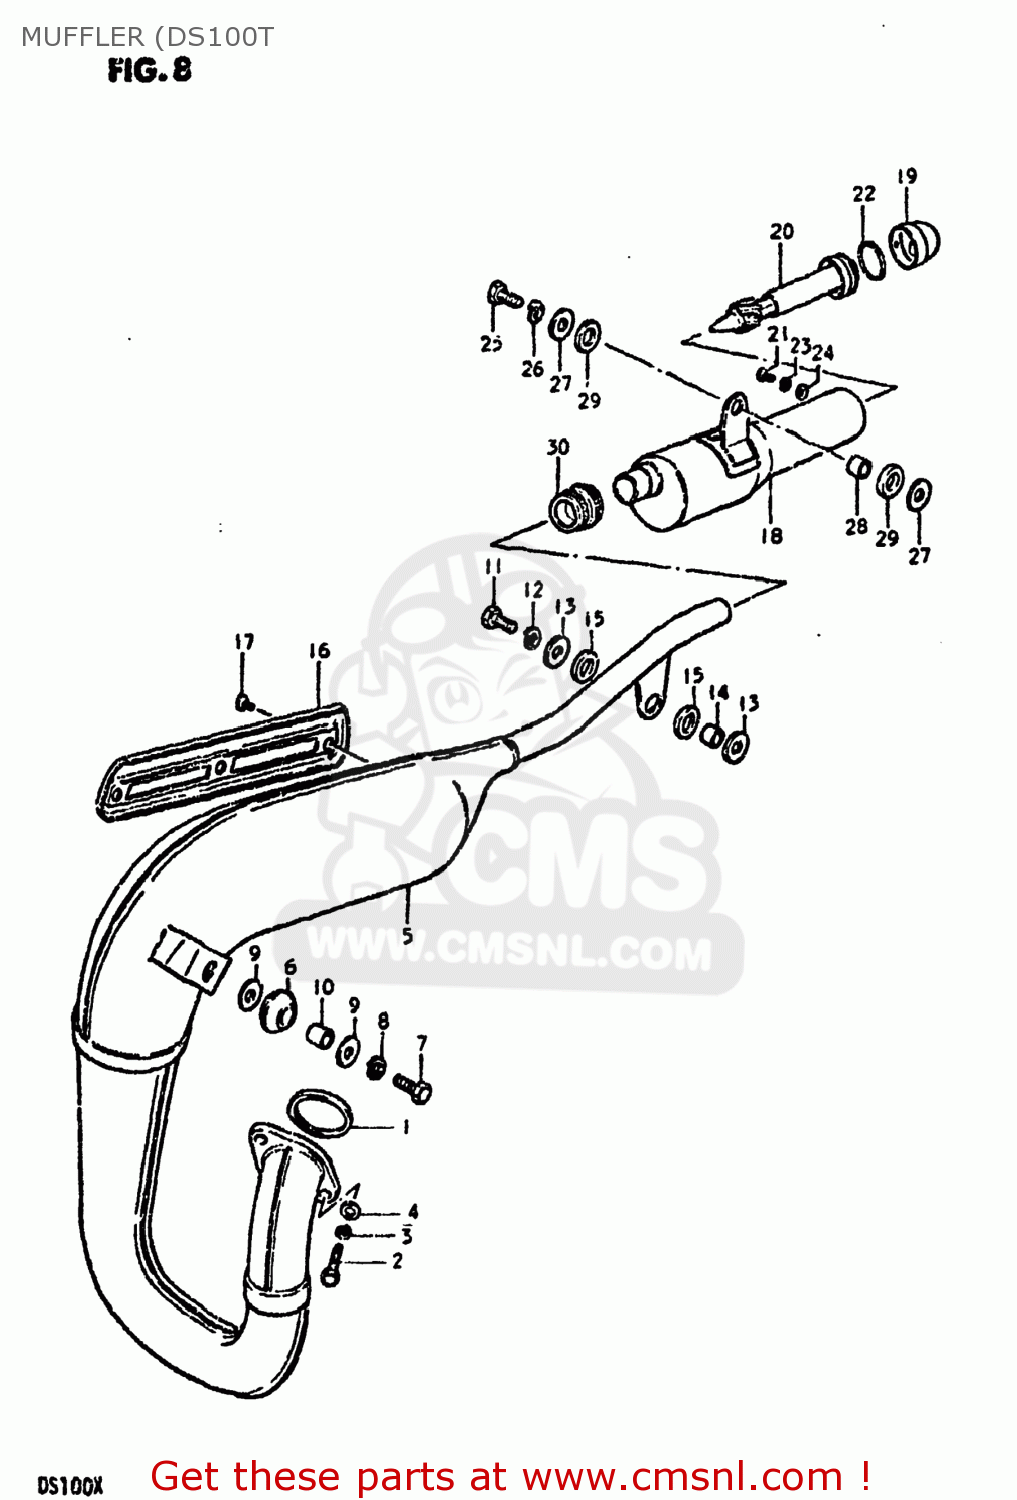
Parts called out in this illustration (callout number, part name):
1	GASKET,EXHAUST PIPE (NAS)
2	SCREW (6X25)
3	LOCK WASHER
4	WASHER
5	BODY,MUFFLER
6	DAMPER,MUFFLER,FR
7	BOLT
8	LOCK WASHER
9	WASHER (8.7X22X2)
10	SPACER (8X12X15)
11	BOLT
12	LOCK WASHER
13	WASHER
14	SPACER (8.6X13.8X9.8)
15	CUSHION
16	COVER,MUFFLER
17	SCREW
18	MUFFLER ASSEMBLY
19	COVER,SECOND MUFFLER TAIL
20	TUBE,MUFFLER CLEAN OUT
21	SCREW(6X8)
22	O-RING (D:3.5 ID:54.4)
23	LOCK WASHER
24	WASHER
25	BOLT
26	LOCK WASHER
27	WASHER
28	SPACER (8.6X13.8X9)
29	CUSHION
30	CONNECTOR,MUFFLER
